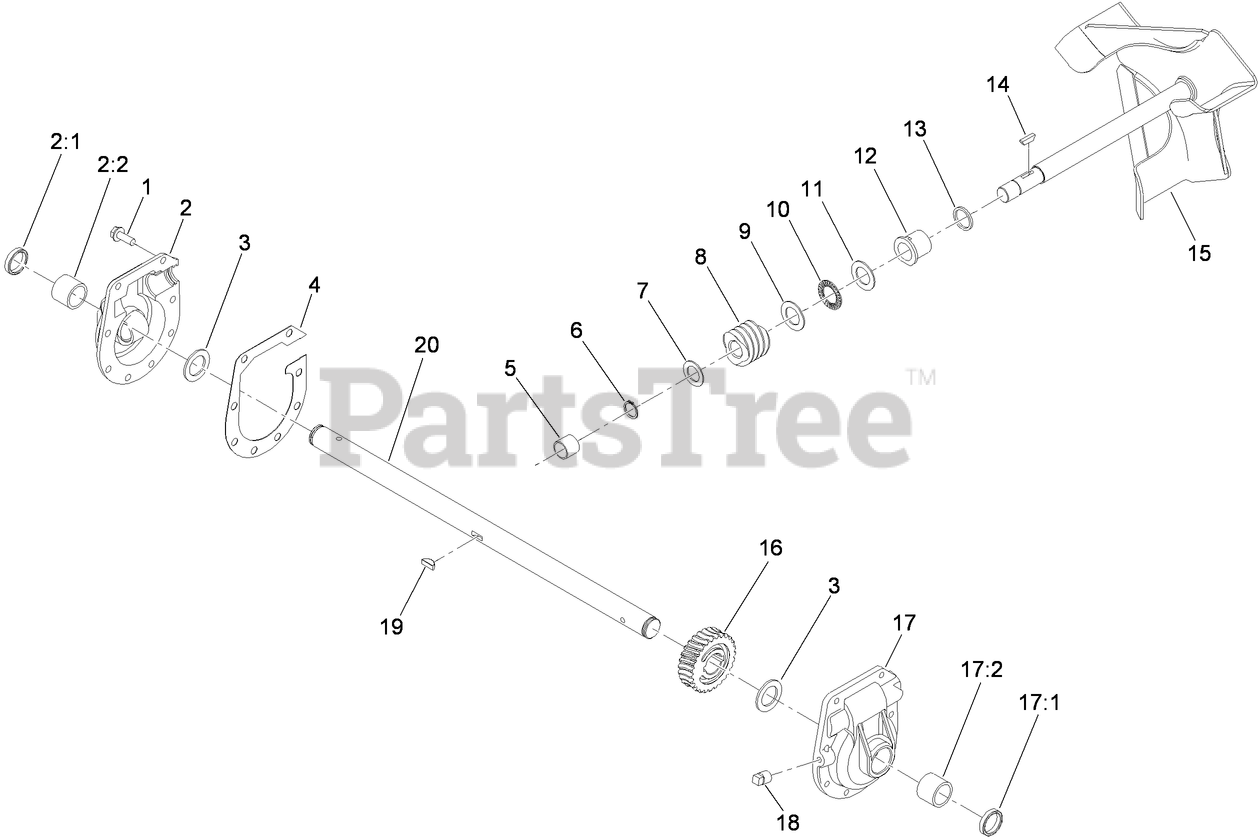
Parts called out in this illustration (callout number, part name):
1	SCREW-TAPTITE
2	RH BUSHING CASE ASM
2:1	SEAL-OIL
2:2	BUSHING-SLEEVE
3	WASHER-THRUST
4	GASKET-CASE, GEAR
5	BUSHING
6	Ring-Snap
7	WASHER-THRUST
9	WASHER-THRUST
10	BEARING-THRUST
11	WASHER-THRUST
12	BUSHING-INPUT
13	RING-QUAD
14	KEY-WOODRUFF
15	IMPELLER SHAFT ASM
16	WORM-GEAR
17	LH BUSHING CASE ASM
17:1	SEAL-OIL
17:2	BUSHING-SLEEVE
18	PLUG-PIPE, SQH
19	KEY-WOODRUFF
20	SHAFT-AUGER
